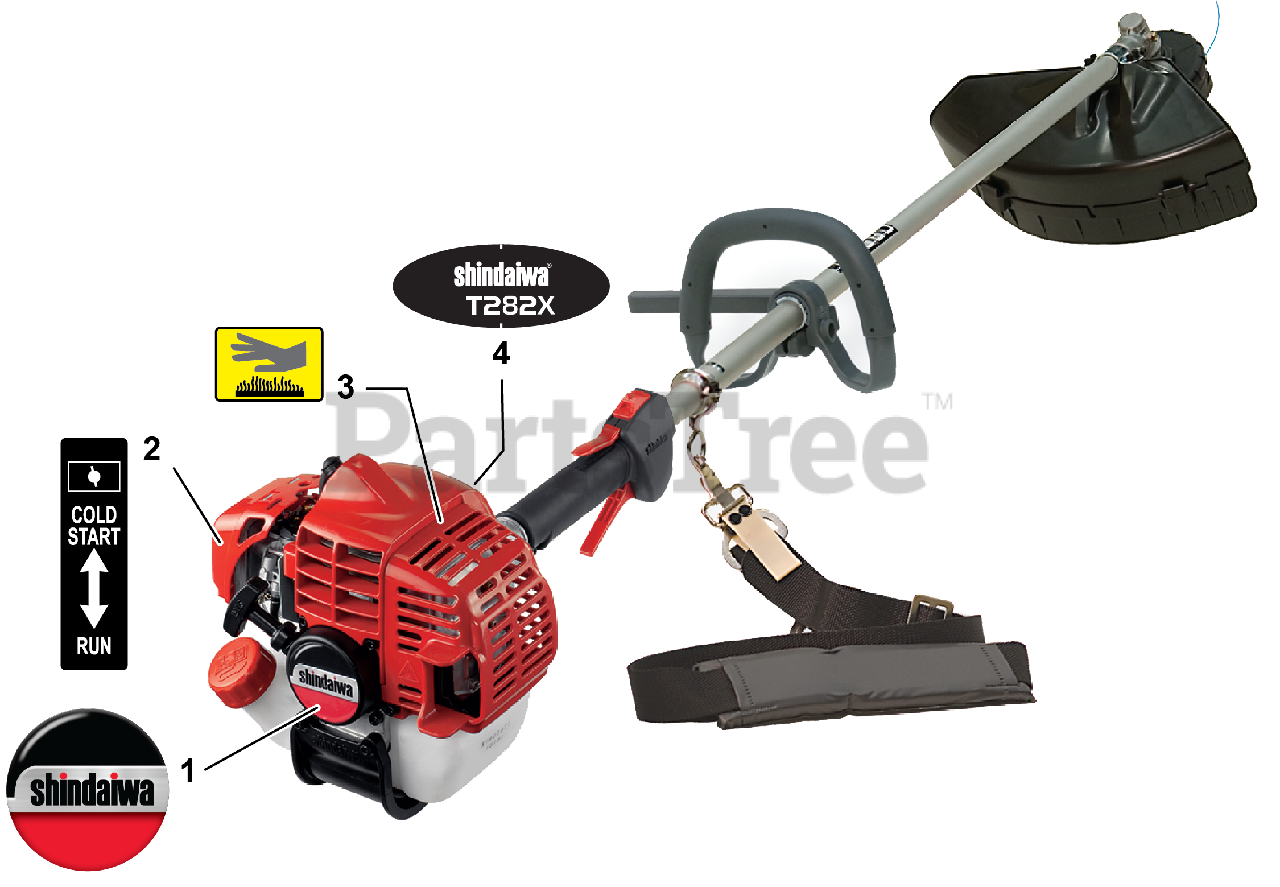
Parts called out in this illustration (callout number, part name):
1	LABEL - RECOIL STARTER
2	LABEL - CHOKE
3	LABEL - CAUTION - HOT
4	LABEL - MODEL T282X
